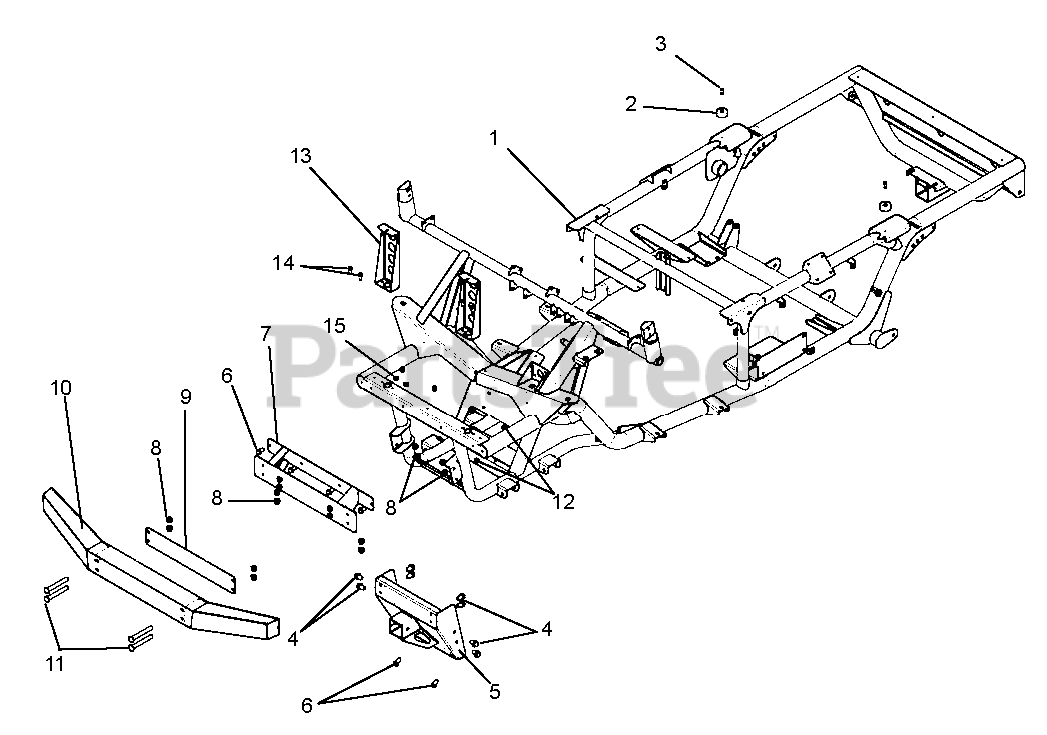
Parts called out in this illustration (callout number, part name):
1	WELDMENT, MAINFRAME
2	BUMPER, RUBBER .625 X 1.50 DIA
3	RIVET, 3/16 X .500 POP
4	HFSS 3/8-16 X 3/4 LG
5	WELDMENT, RECEIVER, FRONT
6	BOLT, SERRATED HEX FLANGE HEAD .312-18 X .75
7	WELDMENT, MNT, BUMPER
8	NUT, SPIN, LOCK FLANGE .375-16
9	PLATE, BACK BUMPER, RED (996123, 125, 146)
10	WELDMENT, BUMPER
11	BOLT, ROUNDHEAD SQUARE NECK .38-16 X 4.0 G5 YWZC
12	NUT, SPIN LOCK FLANGE .312-18
13	HOOD MOUNT BRACKET
14	BOLT, HEX .25-20 X .75 GR5 YWZC
15	NUT, LOCKING FLANGE .25-20 TWZC
